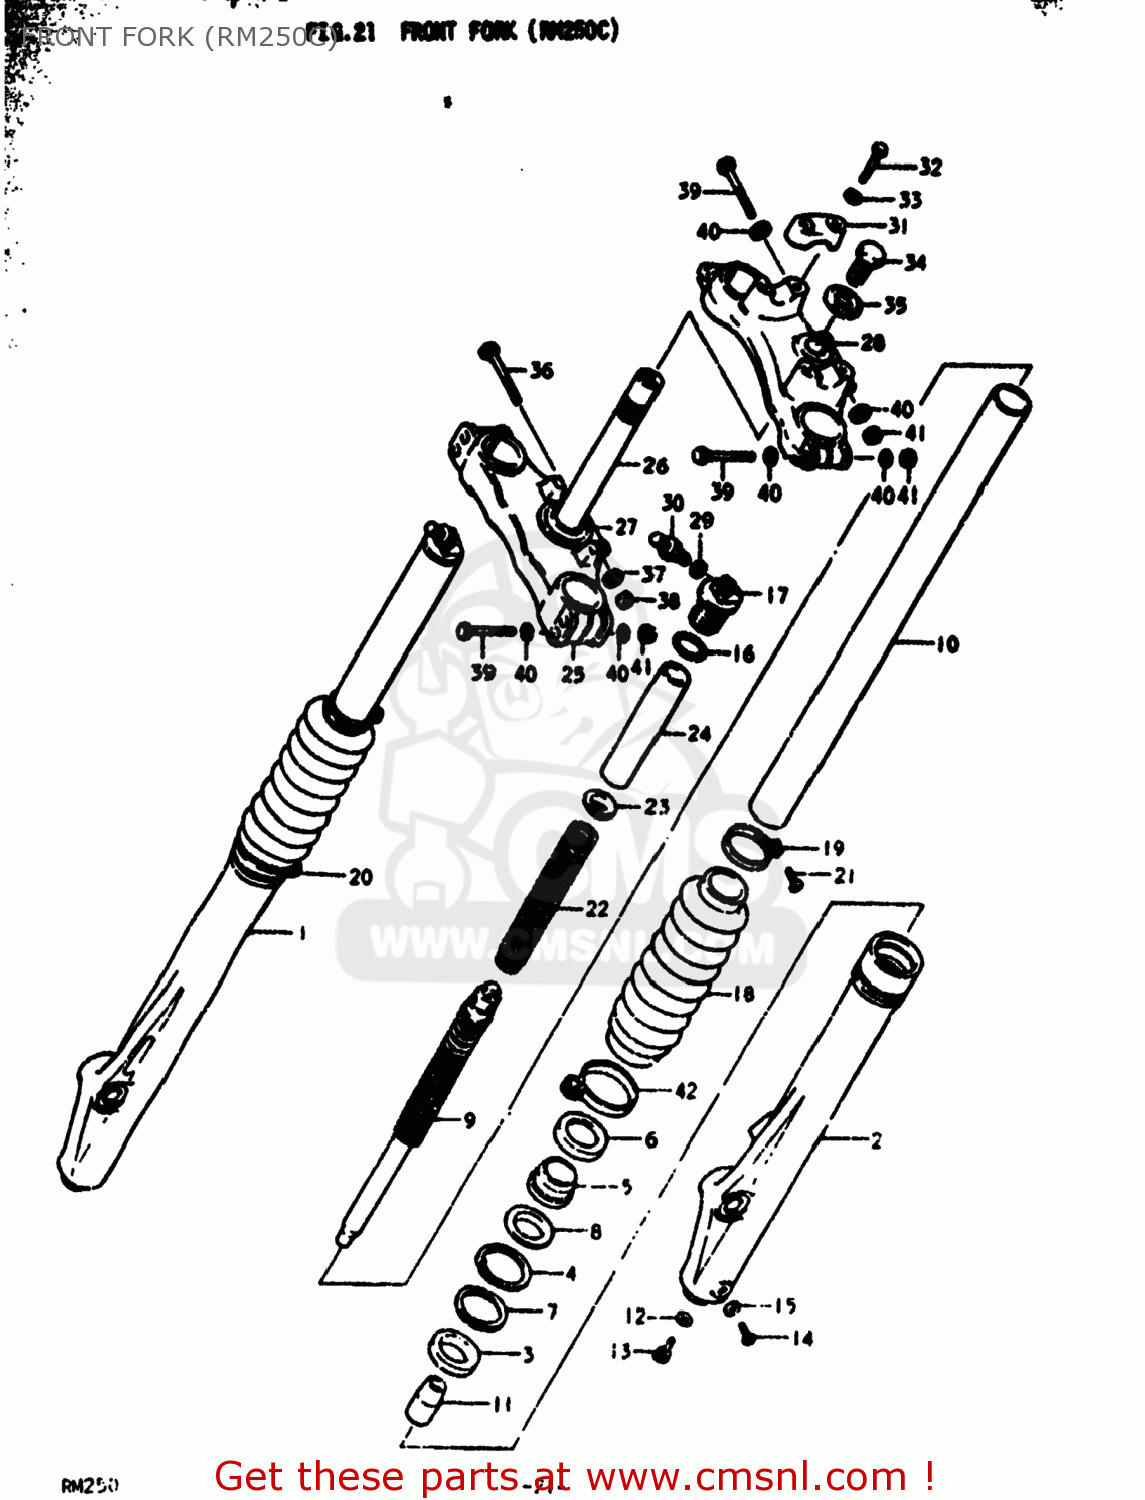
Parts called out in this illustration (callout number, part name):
1	TUBE,OUTER,RIGHT
2	TUBE,OUTER,LEFT
3	OIL SEAL,FRONT FORK
4	CIRCLIP,FORK OIL SEAL
5	DUST SEAL,FRONT FORK
6	GUIDE.FORK DUST
7	WASHER
8	LABEL
9	CYLINDER,FRONT FORK
10	TUBE,FORK,INNER
11	PIECE,OIL LOCK
12	GASKET (NAS)
13	BOLT
14	SCREW
15	GASKET,DRAIN,PLUG (NAS)
16	O RING
17	CAP
18	BOOT
19	BAND,BOOT
20	BAND,FRONT FORK COVER
21	SCREW
22	SPRING
23	GUIDE,FRONT FORK SPRING C
24	SPACER,FRONT FORK SPRING
25	STEM,STEERING
26	STEM,STEERING
27	RACE,STEERING OUTER LWR
28	HEAD,STEERING STEM
29	O RING
30	VALVE
31	HOLDER,HANDLEBAR
32	Bolt
33	LOCK WASHER
34	BOLT,STEERING STEM HEAD
35	WASHER
36	BOLT 10X60
37	LOCK WASHER
38	NUT
39	BOLT
40	WASHER
41	NUT
42	BAND,FRONT FORK COVER
